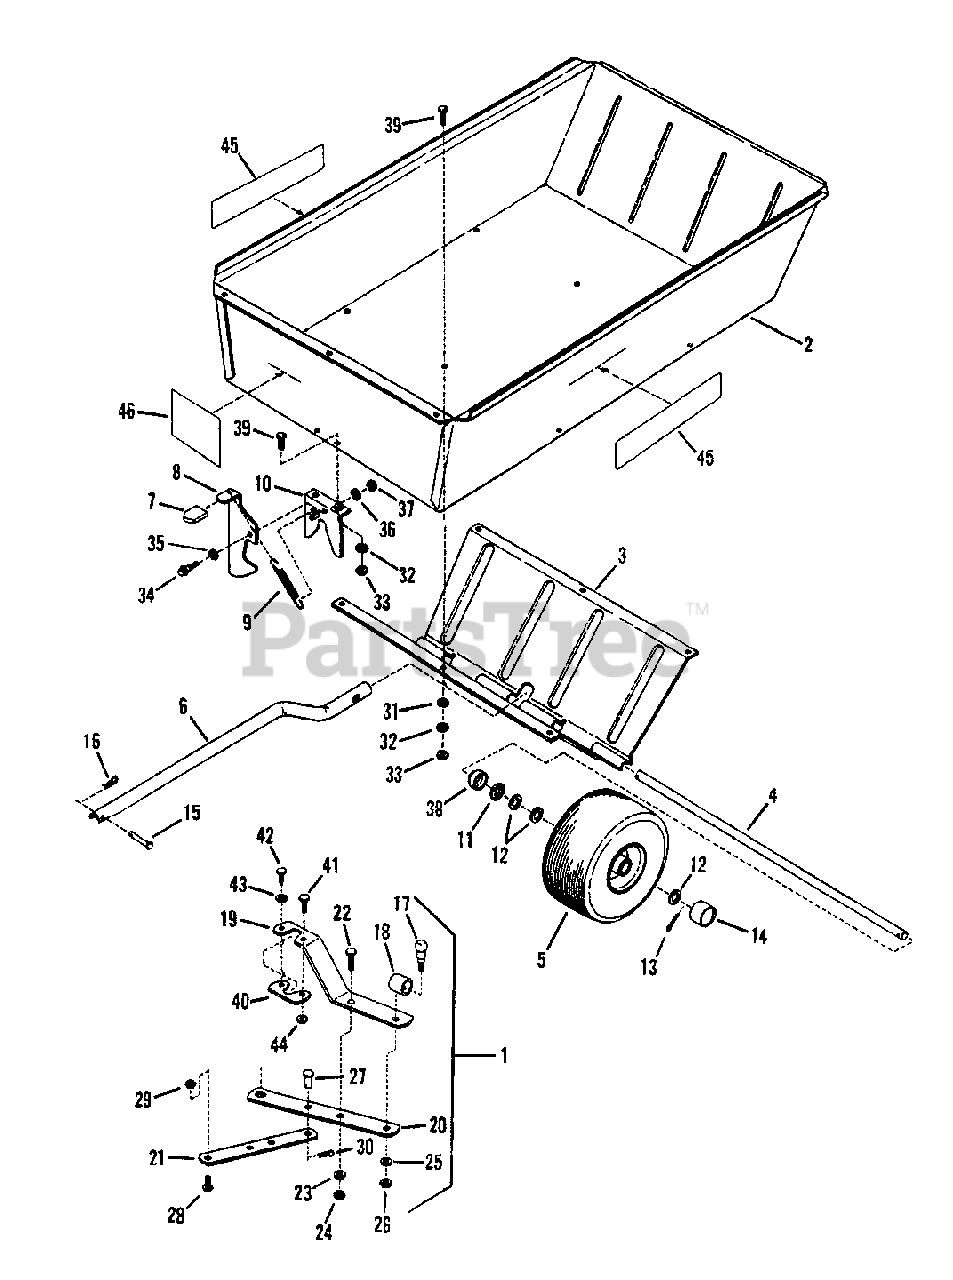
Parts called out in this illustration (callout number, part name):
1	ASSEMBLY, Hitch
2	BODY, Wagon Cart
3	SUPPORT, Axle
4	AXLE
5	ASSEMBLY, Wheel/Tire, Pneumatic
6	TONGUE
7	GRIP, Latch
9	SPRING, Latch
10	YOKE
11	WASHER, Felt
12	WASHER, 3/4"
13	PIN, 5/32 x 1" Cotter
14	COVER, Dust
15	PIN, 3/8 x 2-1/4" Clevis
16	HAIRPIN, 3/32"
17	BALL, Hitch
18	COLLAR, Hitch
19	BAR, Upper Draw
20	BRACE, Draw Bar
21	BAR, Lower Draw
22	SCREW, 3/8-24 x 1" Hex Head Cap, Grade 5
23	WASHER, 3/8" Split Lock
24	NUT, 3/8-24 Hex, Grade 2
25	WASHER, 7/16" Split Lock
26	NUT, 7/16-20 Hex, Grade B
27	PIN, Hitch Clevis
28	SCREW, 1/2-20 x 1" Hex Head Cap, Grade 2
29	NUT, 1/2-20 Hex Jam Lock
30	HAIRPIN, 3/32 x 1-19/32"
31	RETAINER, 1/4" Bolt
32	WASHER, 1/4" Internal Tooth Lock
33	NUT, 1/4-20 Hex
34	BOLT, 5/16-18 Shoulder
35	WASHER, Spring
36	WASHER, 5/16" Split Lock
37	NUT, 5/16-18 Hex
38	DUST-CAP
39	BOLT, 1/4-20 x 3/4" Short Neck Carriage, Grade 5
40	CLIP, Retaining
41	SCREW, 5/16-18 x 3/4" Hex Head Cap, Grade 2
42	SCREW, 5/16-18 x 1/2" Hex Head Cap, Grade 2
43	WASHER, 5/16" Internal Tooth Lock
44	NUT, 5/16-18 Hex Center Lock
45	DECAL, Snapper
46	DECAL, Maximum Load
